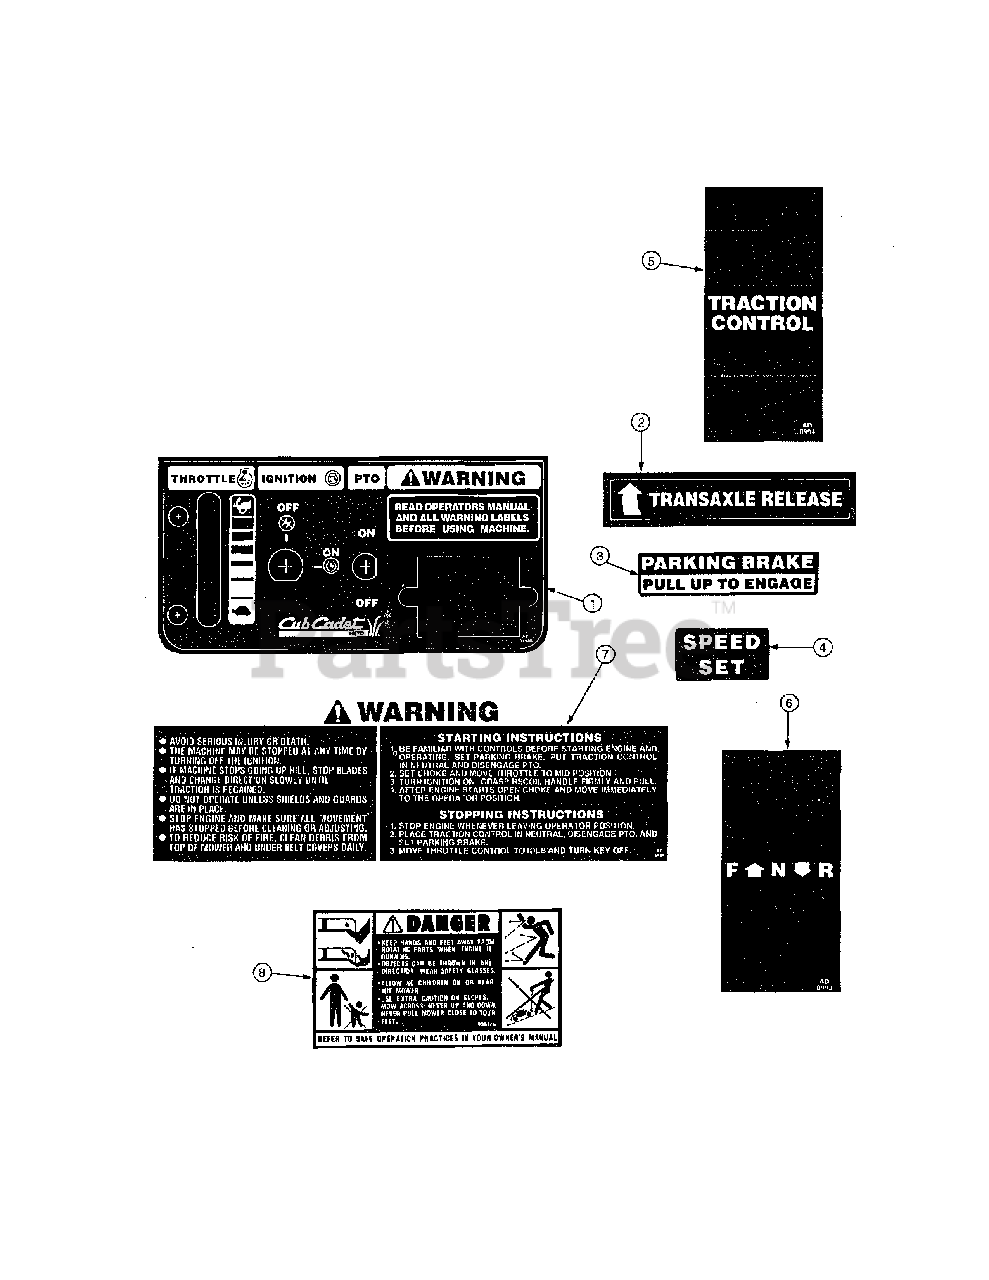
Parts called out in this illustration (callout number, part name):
1	Graphic, Control Panel
2	Graphic, Transaxle Release
3	Graphic, Park Brake
4	Graphic, Speed Set
5	Graphic, Traction Control
6	Graphic, F-N-R
7	Graphic, Warning
8	Graphic, Danger
